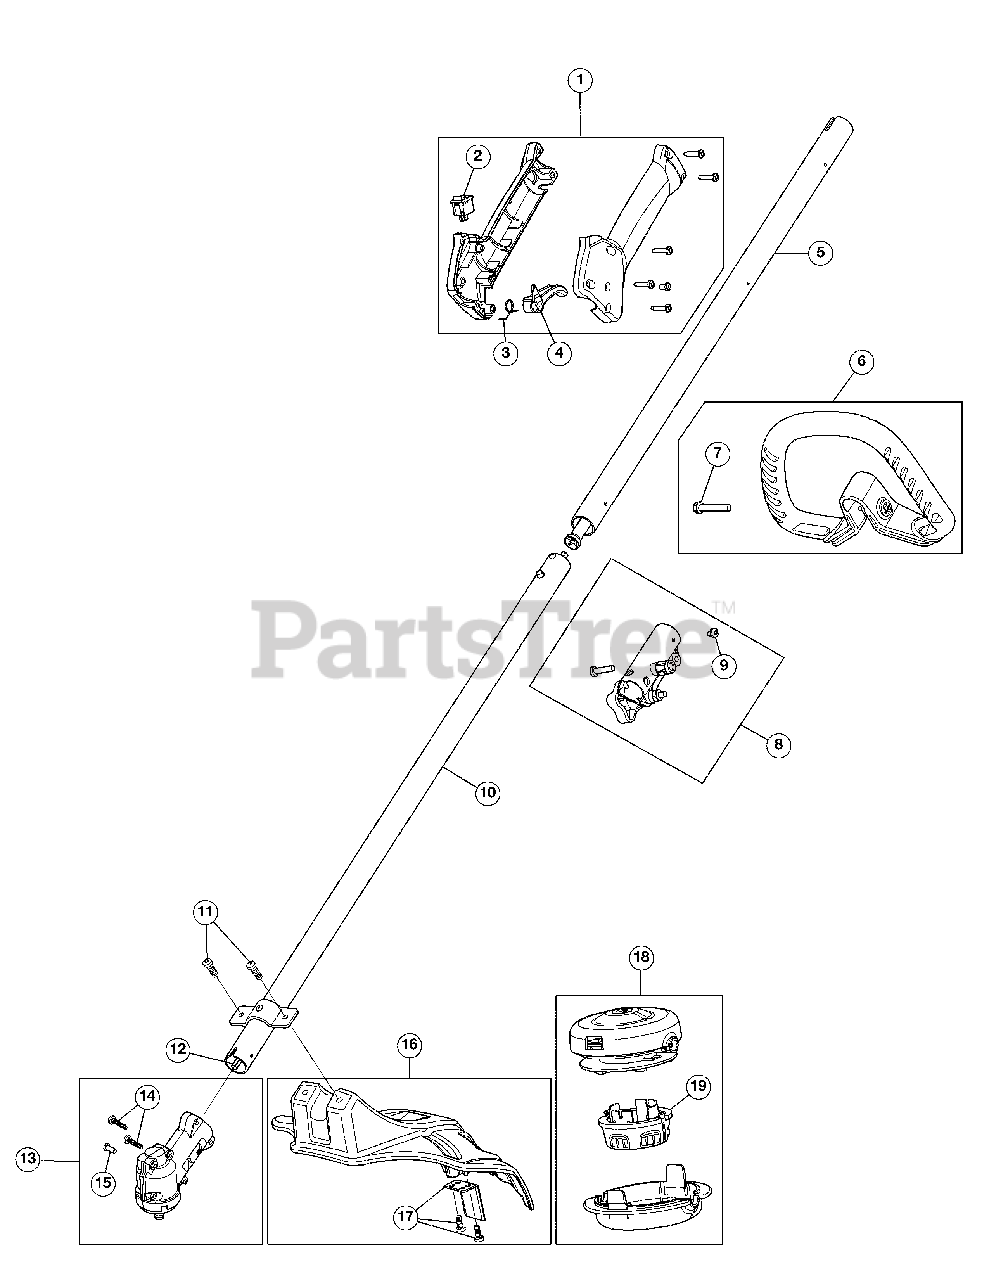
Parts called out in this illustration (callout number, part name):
1	Throttle Housing Assembly (Incl. 2 - 4)
2	Trigger Switch Assembly
3	Throttle Trigger Spring
4	Throttle Trigger
5	Upper Drive Shaft Assembly
6	D-Handle Assembly (Incl. 7)
8	Split Boom Coupler (Incl. 9)
9	Coupler Anti-Rotation Screw
10	Lower Drive Shaft Housing
11	Shield Mounting Screws
12	Lower Flexible Drive Shaft
13	Gearbox Assembly (Incl. 14 and 15)
14	Gearbox Mounting Hardware
15	Gearbox Anti-Rotation Screw
16	Shield Assembly (Incl. 17)
17	Blade Assembly
18	Cutting Head Assembly (Incl. 19)
19	Bump Knob
